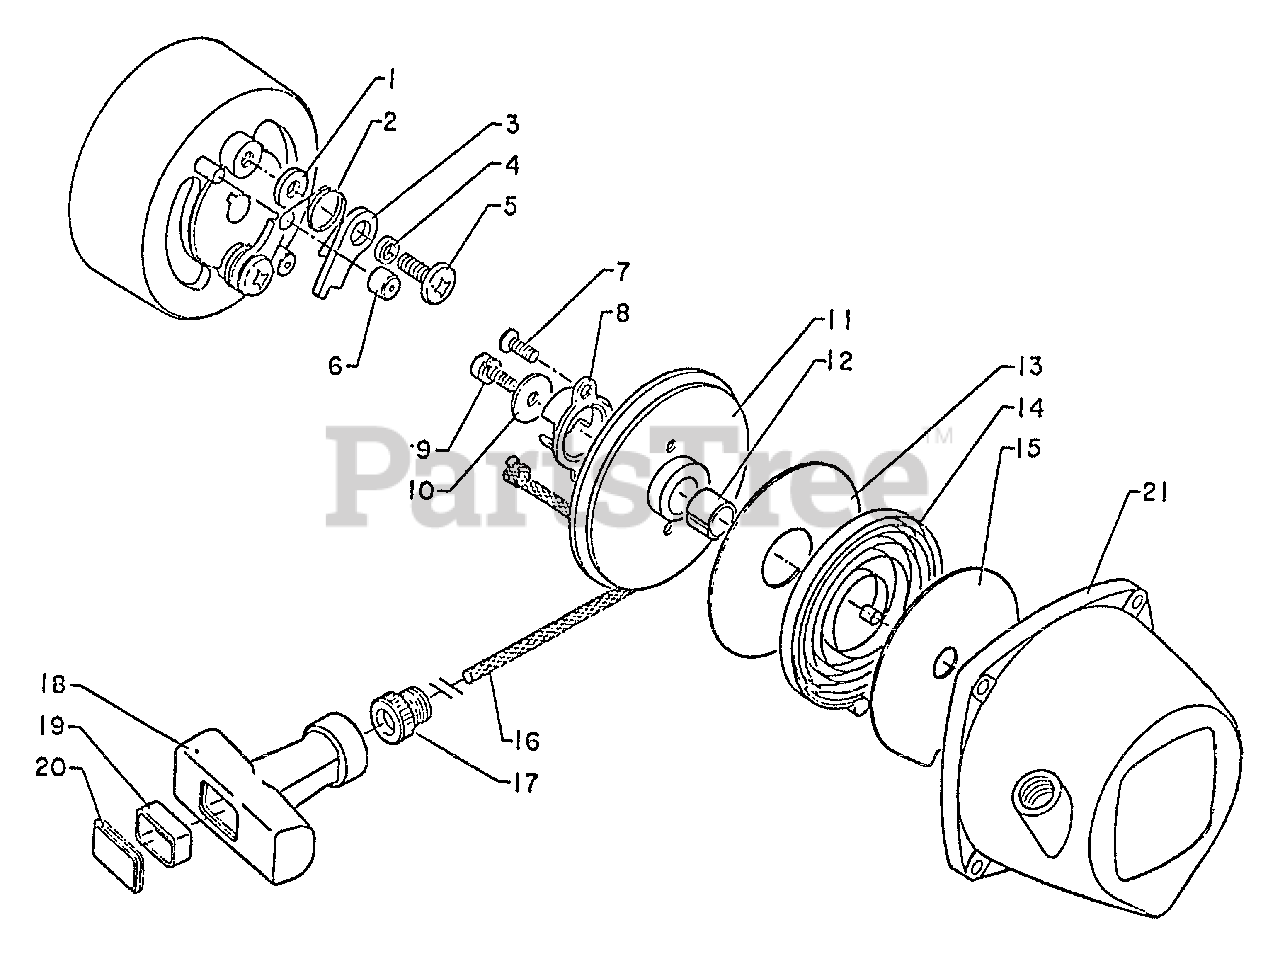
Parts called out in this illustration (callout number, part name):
1	WASHER, ADJUST
2	SPRING, RETURN
3	PAWL, STARTER
4	SPACER 5.2×8×2.1
5	SCREW
7	SCREW 4×8
8	CATCHER, PAWL
9	SCREW 4×8
9	WASHER, SPRING 4 MM
10	WASHER 4.1×15.5×1T
11	REEL, ROPE
13	PLATE, STARTER
14	SPRING, RECOIL
15	PLATE, STARTER
16	ROPE, STARTER 3.5×850
17	GUIDE, ROPE
18	GRIP, STARTER
20	COVER, HANDLE
21	CASE, STARTER
